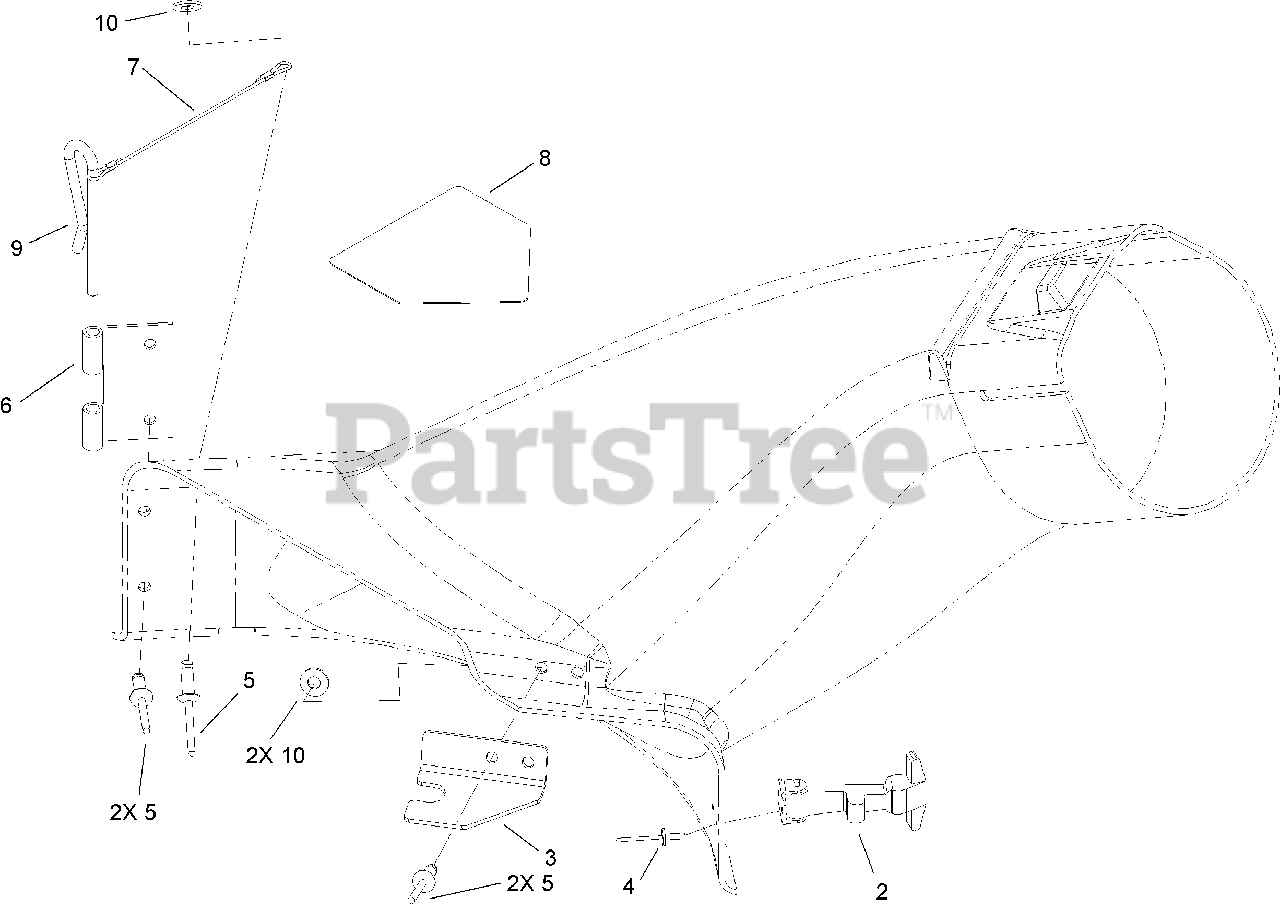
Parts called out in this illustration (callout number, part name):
2	HANDLE ASM
3	LATCH-ELBOW, BAGGER
4	RIVET-POP
6	BRACKET-MOUNTING, CHUTE
8	DECAL-DANGER, SHIELD
9	PIN-LOCKING, CHUTE
10	WASHER-FLAT
